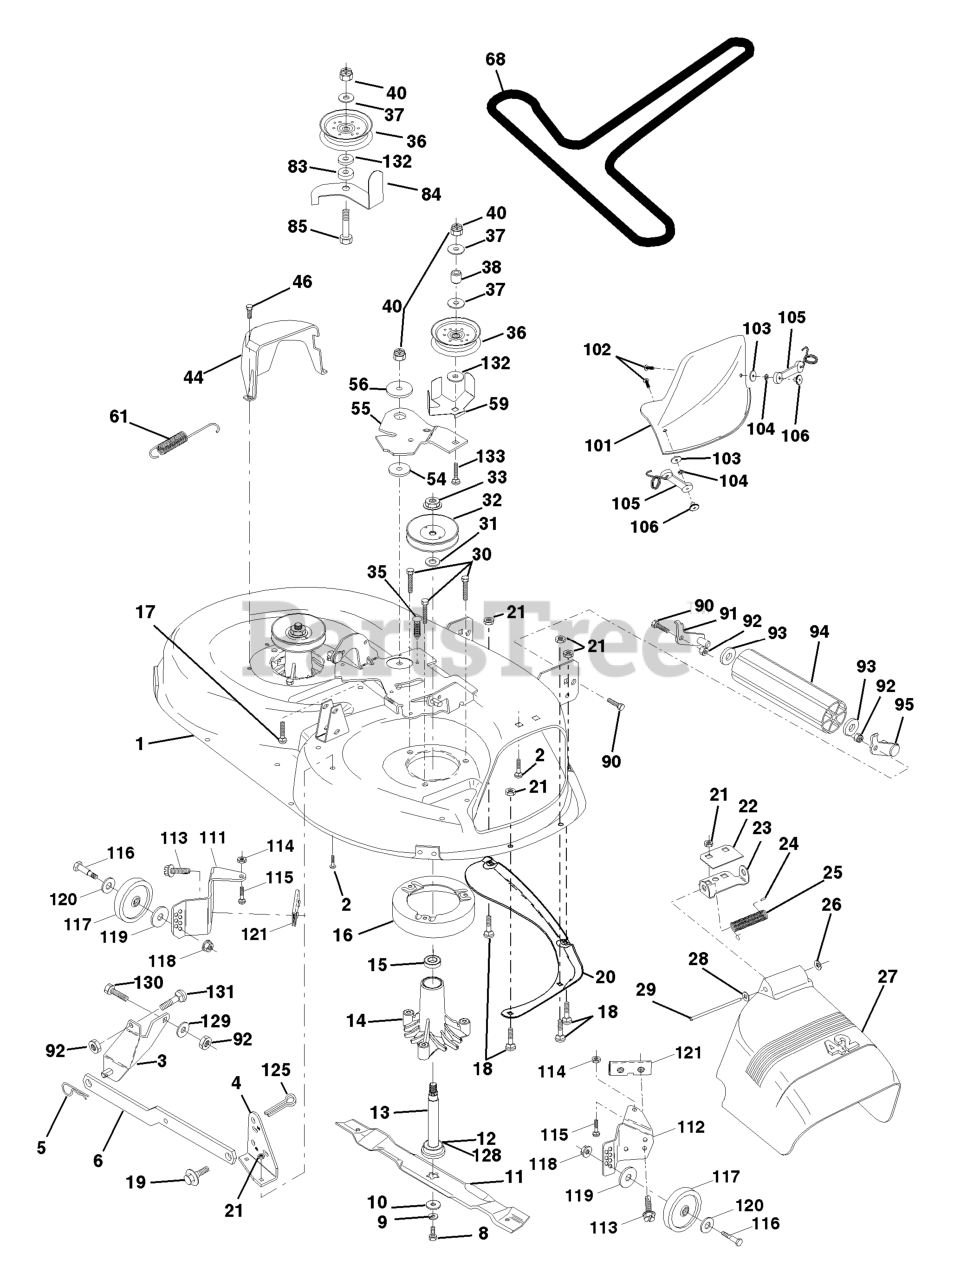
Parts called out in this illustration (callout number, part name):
1	DECK 42"
2	RP BOLT 5/16-18 X3/4 ZN/YEL GR
3	BRKT ASM SWAY BAR
4	BRKT DECK SW BAR
5	RETAINER-SPRNG RB
6	REAR SUSP ARM
8	BLADE BOLT
9	LOCKWASHER
10	WASHER.BLADE
11	BLADE.42".MULCH
12	BEARING.BALL.#6204.(MANDREL)
13	SHAFT ASM VENT
14	HOUSING.MANDREL.VENTED (MACHD)
16	STRIPPER
17	BOLT CARRIAGE
18	BOLT
19	BOLT SHD 5/16-18
20	BAFFLE
21	LOCKNUT
22	STIFFENER BRACKET
23	DEFLECTOR BRACKET
24	CAP-SLEEVE LT
25	SPRING TORSION
26	NUT PUSH M
27	SHIELD.DEFLECTOR.MOWER.42".BLK
28	Washer 11/32 X 5/8 X 16 Ga
29	ROD.HINGE
30	SCREW THDROL ROLLING WASHER HD
31	WASHER
32	PULLEY/MANDREL
33	NUT
35	FASTENER.XMAS.TREE
36	FLAT IDLER PULLEY
37	WASHER
38	IDLER SPRING SPACER
44	GUARD MANDREL LH BLACK
46	SCREW.1/4-20X5/8
54	HARDENED WASHER
55	IDLER ARM
56	SPACER RETAINER
59	GUARD, BELT
61	SPRING EXTENSION
68	V-BELT TRIPATH
84	KEEPER.BELT.IDLER
85	BOLT
90	BOLT
91	BRACKET LH (A)
92	NUT
93	Washer 17/32 X 7/8 X 16 Ga
94	NOSE ROLLER
95	BRACKET RH (B)
101	COVER MULCH 42"
102	SCREW
104	LOCKWASHER #10
105	LATCH ASSY
106	WELDNUT
111	BRACKET WHEEL GAUGE LH 42" DK
112	BRACKET WHEEL GAUGE RH 42" DK
113	SCREW.THDROL.5/16-18X3/4.TTY
114	NUT
115	BOLT.CARR.5/16-18X1/2
116	BOLT M
117	WHEEL.GAUGE.BLK.4.93
118	LOCKNUT
119	WASHER.5/16.FLAT.STE.STD.
120	Washer 17/32 x 15/16 x 12 Ga.
121	BRACKET.EXTRUDED.GAGE.WHEEL
125	Cotter Pin
128	WASHER FELT
129	WASHER
130	BOLT
131	BOLT D
132	Washer 13/32 x 1-3/8 x 3 Ga
